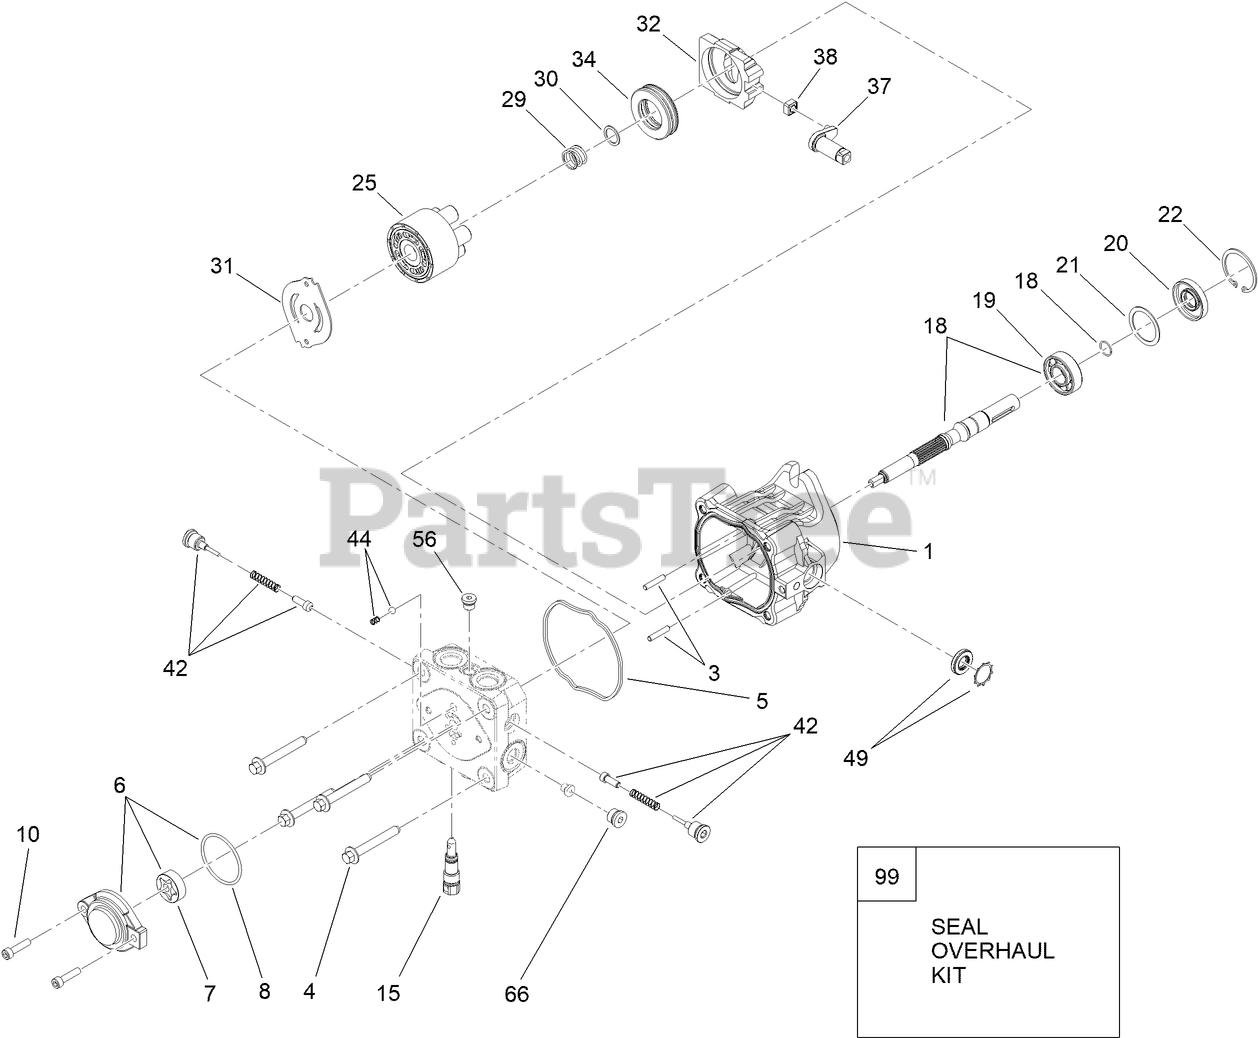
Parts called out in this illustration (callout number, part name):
1	HOUSING KIT
3	PIN-HEADLESS, STRAIGHT
4	BOLT-HF
6	CHARGE PUMP KIT
7	GEROTOR ASM
8	O-RING
10	CAPSCREW
15	BYPASS VALVE KIT
18	INPUT SHAFT KIT
19	BEARING-BALL
20	SEAL-LIP
21	SPACER
22	RING-RETAINING
25	CYLINDER BLOCK KIT
29	SPRING-BLOCK
30	WASHER-THRUST
31	PLATE-VALVE
32	SWASHPLATE-VARIABLE
34	BEARING-THRUST
37	ARM-TRUNNION, TAPERED SQUARE
38	GUIDE-SLOT
42	VALVE-CHECK (W/POPPET)
44	CHARGE RELIEF VALVE KIT
49	TRUNNION SEAL KIT
56	PLUG-HSH
66	PLUG-HSH
